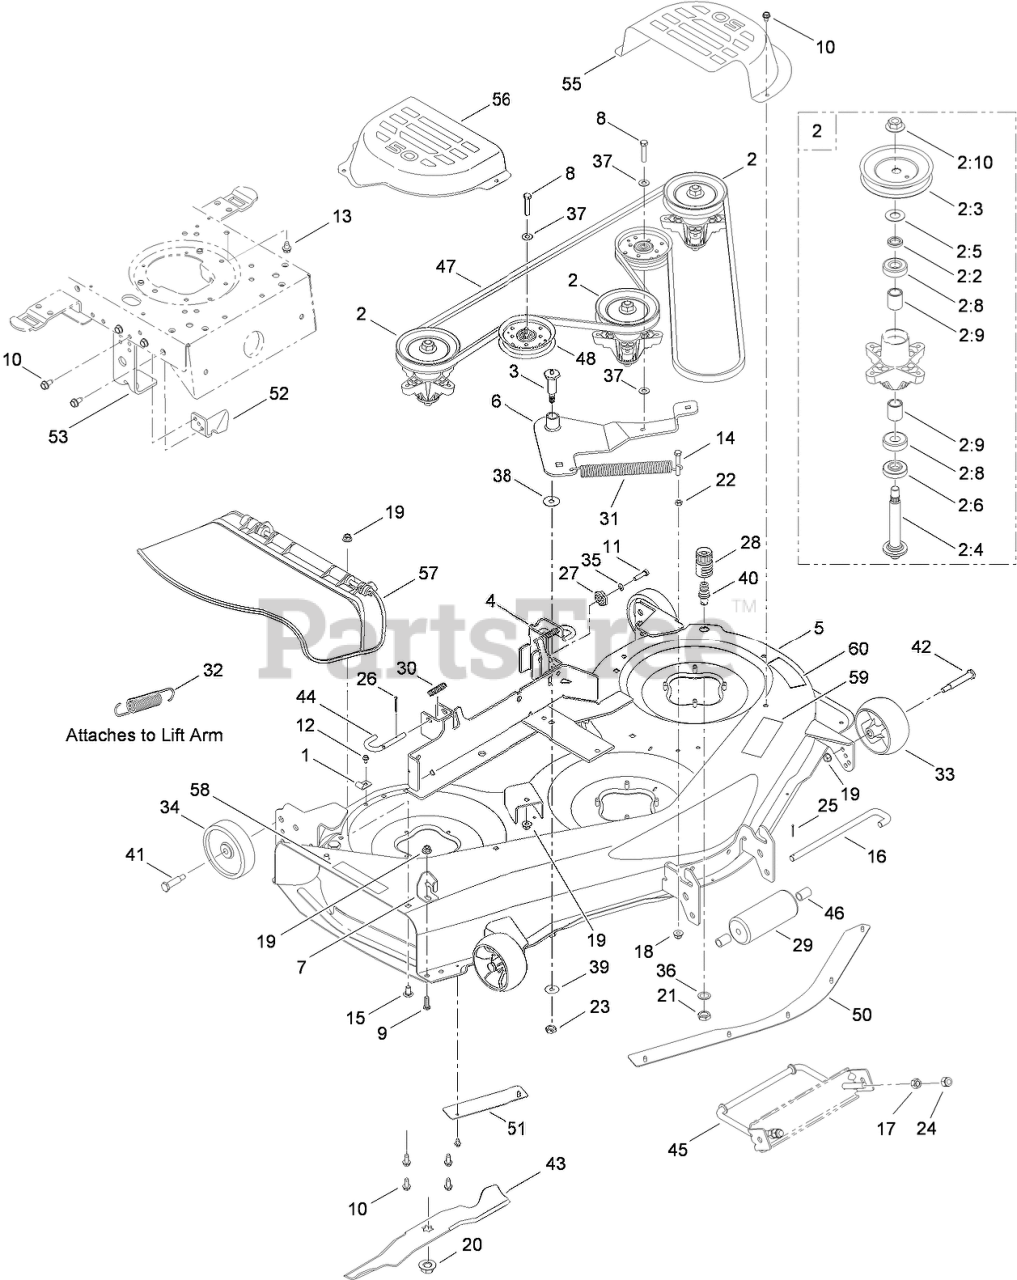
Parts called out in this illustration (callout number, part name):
1	BRACKET-RETAIN, HOOK
2	SPINDLE ASM
2:2	SPACER
2:3	PULLEY
2:4	SHAFT-SPINDLE, BLADE (STAR)
2:5	WASHER-FLAT
2:6	SPACER
2:8	BEARING-BALL
2:9	SPACER
2:10	NUT-LOCK, FLANGE
3	BOLT SHOULDER ASM
4	LH HANGER BRACKET ASM
5	50 INCH SIDE DISCHARGE DECK ASM
6	IDLER ASM
7	STOP-CHUTE
8	SCREW-HH
9	SCREW-HH
10	SCREW-TAP
11	SCREW-HH
12	SCREW-HWHTF
13	SCREW-TAP
14	SCREW-HH
15	BOLT-CARR
16	PIN-ROLLER
17	NUT-HEX
18	NUT-LOCK, FLANGE
19	NUT-LOCK, FLANGE
20	NUT-LOCK, FLANGE
21	NUT-HEX
22	NUT-HEX
23	NUT-HEX
24	NUT-LOCK, HEX (NYLON)
25	PIN-COTTER
26	PIN-COTTER
27	GEAR-ADJUSTMENT, DECK
28	ADAPTER-NOZZLE, WATER
29	ROLLER-FRONT
30	SPRING-COMPRESSION
31	SPRING-EXTENSION
32	SPRING-LIFT, ASSIST
33	WHEEL-DECK, FRONT
34	BOLT-CARR
35	WASHER-LOCK
36	WASHER-LOCK
37	WASHER-FLAT
38	WASHER-FLAT
39	WASHER-BELL
40	NOZZLE-WATER, DECK
41	BOLT-SHOULDER
42	BOLT-SHOULDER
43	BLADE-17.90 INCH
44	PIN-HANDLE, DECK RELEASE
45	ROD-FRONT, ADJUST
46	SPACER
47	BELT-V, SECTION A
48	PULLEY-IDLER
50	SKIRT-CENTER
51	SKIRT-RH
52	BRACKET-CLUTCH
53	BRACKET-DECK, UP STOP
55	COVER-BELT, LH
56	COVER-BELT, RH
57	CHUTE DEFLECTOR ASM
58	DECAL-DANGER
59	DECAL-BELT ROUTING, DECK
60	DECAL-DANGER, DECK
